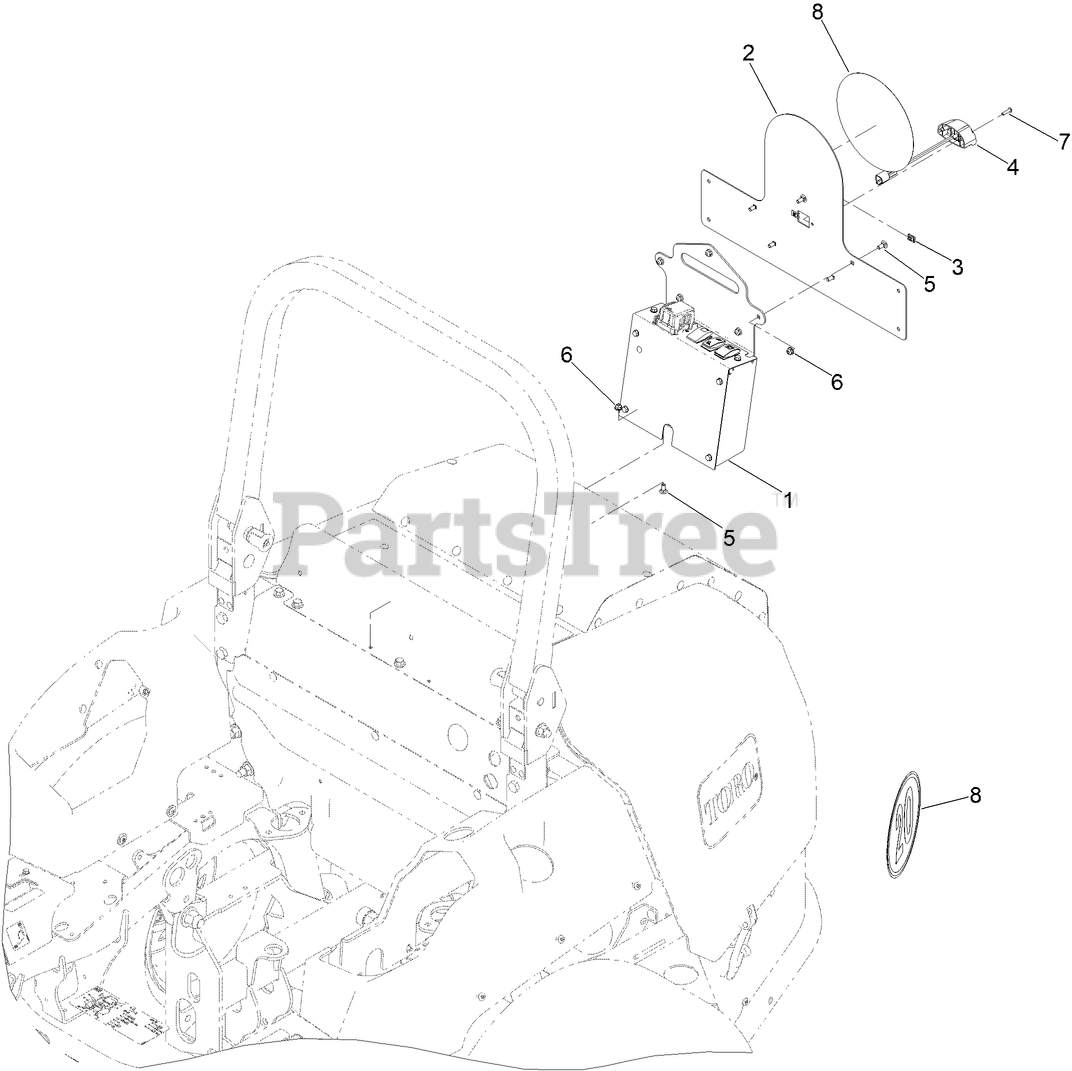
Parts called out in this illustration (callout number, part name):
1	CONTROL PANEL ASM
2	MOUNT-LICENSE, SPEED
3	SCREW-PPH
4	LIGHT-PLATE, LICENSE (ECE)
5	SCREW-CARR
6	NUT-HF
7	NUT-LOCK
8	DECAL-SPEED (20KPM)
99	DECAL-SPEED, 10 KPH
